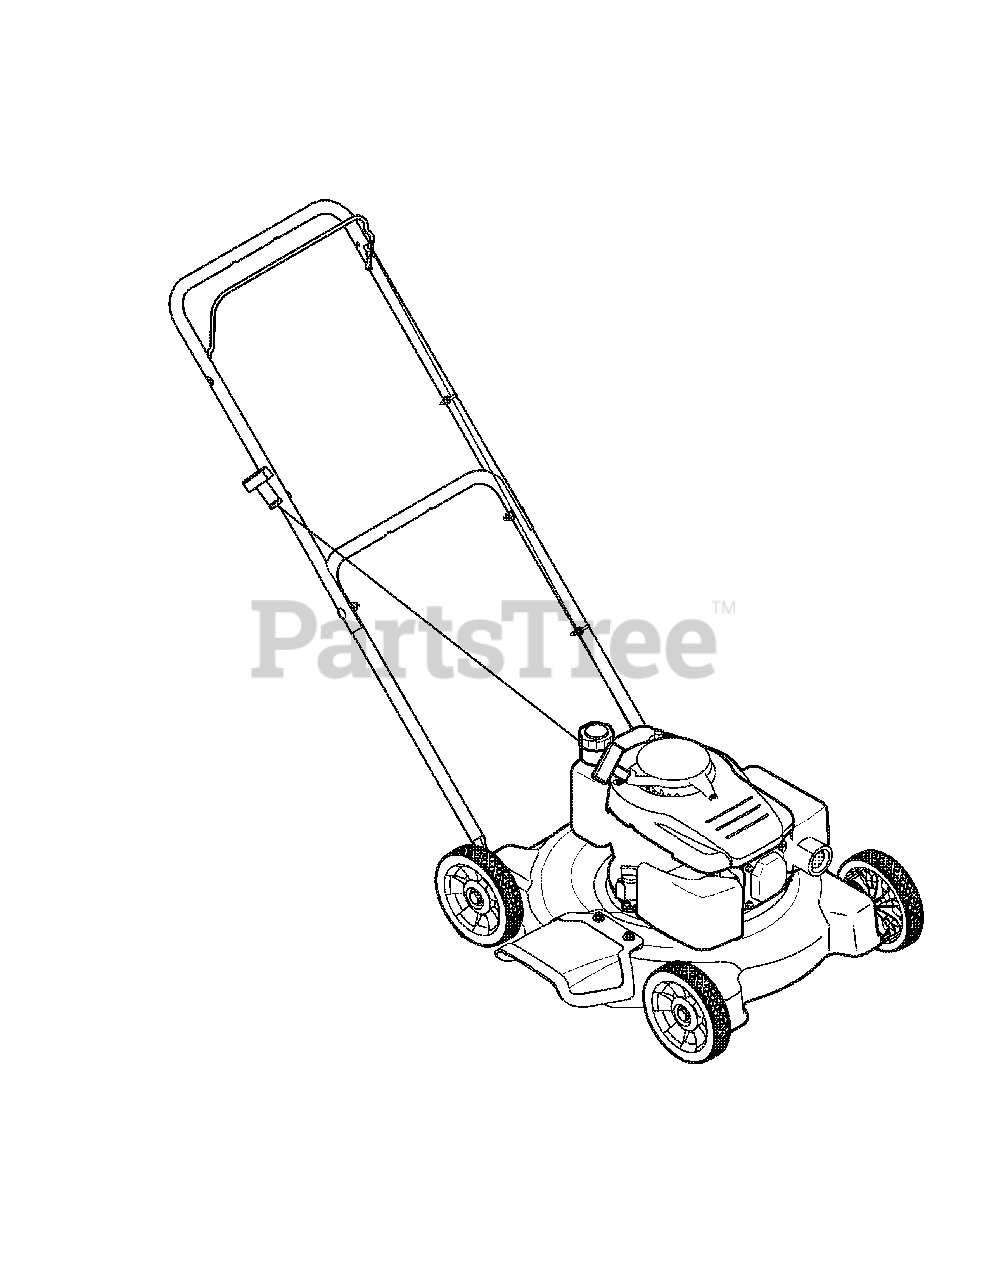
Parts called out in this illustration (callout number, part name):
NA	Drive Belt
NA	Drive Cable
NA	Grass Bag
